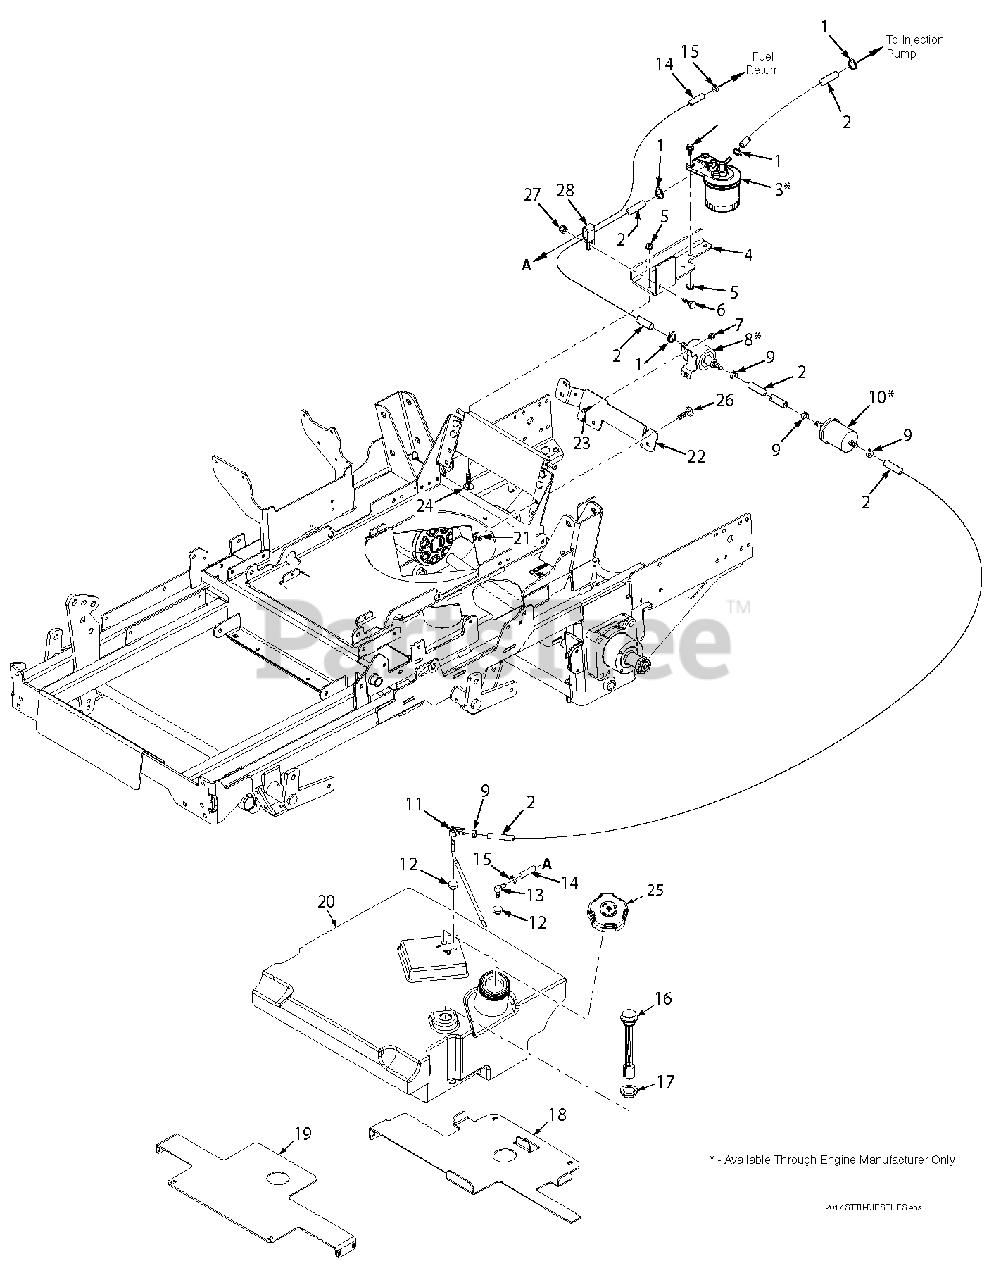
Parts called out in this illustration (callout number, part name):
1	Hose Clamp, 0.69" Dia.
2	Fuel Hose, 5/16" ID. Non-Perm.
3	Fuel Filter, Kubota
4	Bracket, Fuel Filter Mounting
5	Nut, Serr. Flng. 5/16-18
6	Bolt, Carriage 5/16-18 x 3/4"
7	Nut, Hex Elastic Stop 1/4-20
8	Fuel Pump, Kubota
9	Clamp, Fuel Supply Hose
10	Fuel Pre-Filter, Kubota
11	Valve, Shutoff Assy
12	Bushing, 0.56" Dia. Viton
13	Fitting, Return
14	Fuel Return Hose, 3/16"
15	Clamp, Fuel Return Hose
16	Fuel Gauge Assy., 8"
17	Seal, Fuel Gauge
18	Rear Support, Fuel Tank
19	Front Support, Fuel Tank
20	Fuel Tank Assembly
21	Nut, Serr. Flng. 1/4-20
22	Mounting Bracket, Fuel Pump
23	Capscrew, 1/4-20 x 3/4"
24	Bolt, Carriage 5/16-18 x 3/4"
25	Fuel Cap
26	Bolt, Carriage 1/4-20 x 3/4"
27	Nut, Flange Elastic Stop Nut, 5/16-18
28	Clamp, Hose
